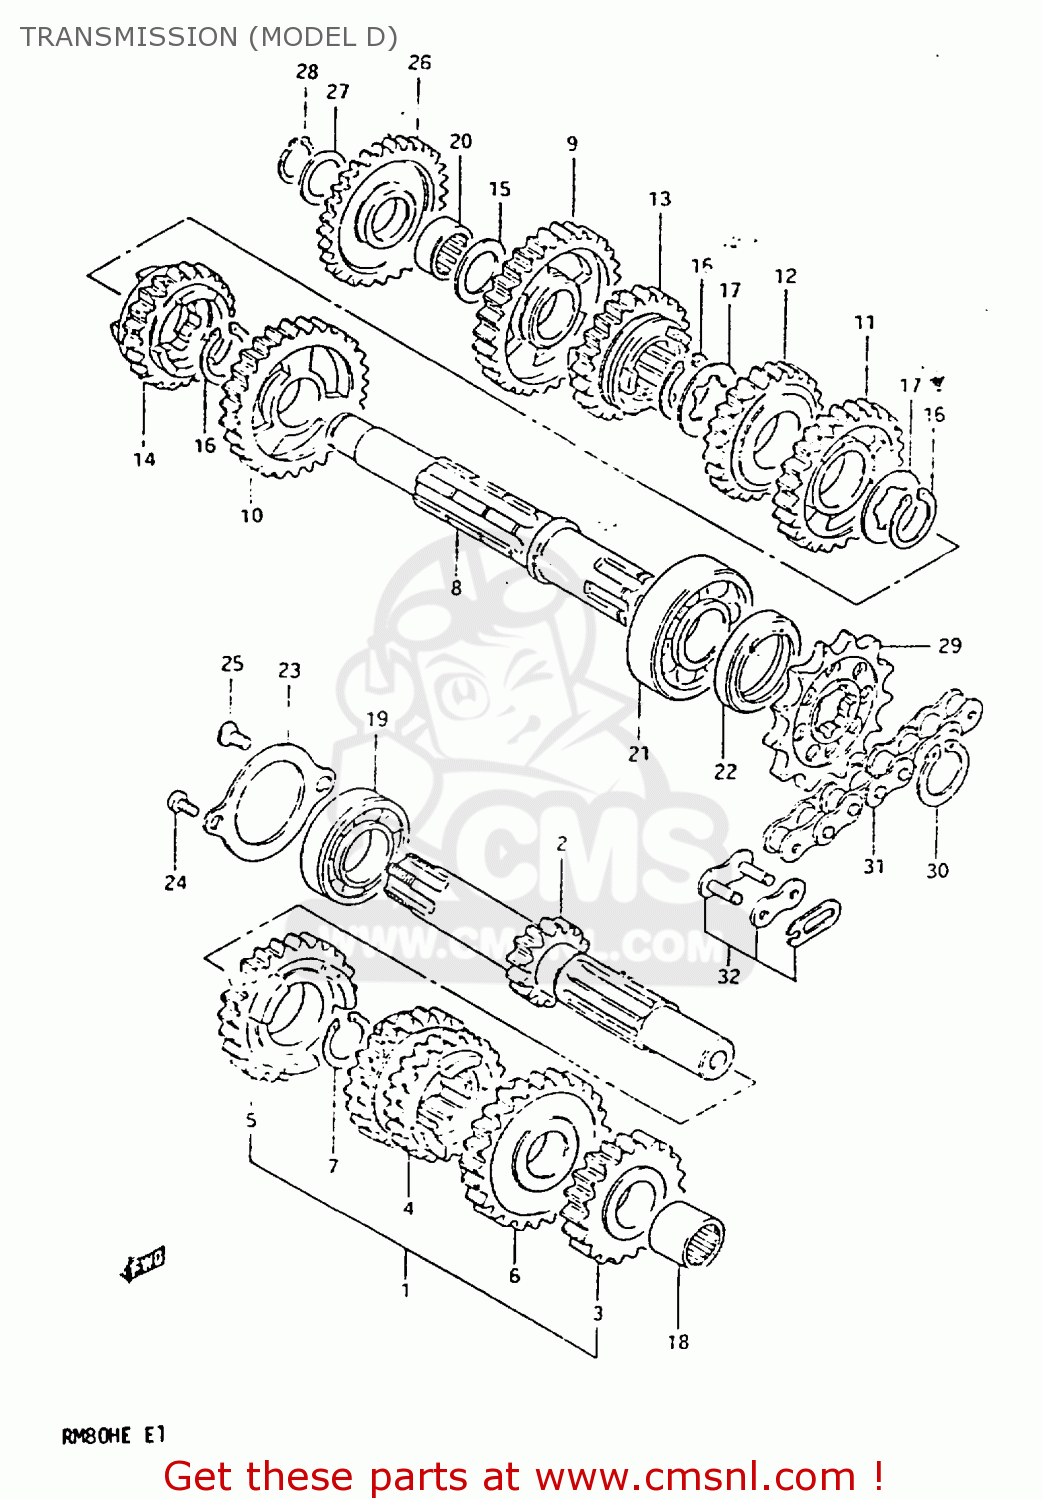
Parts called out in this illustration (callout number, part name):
1	SHAFT,COUNTER
2	SHAFT,COUNTER
3	GEAR,SECOND DRIVE
4	GEAR,THIRD/FOURTH DRIVE
5	GEAR,FIFTH DRIVE
6	GEAR,SIXTH DRIVE
7	CIRCLIP
8	SHAFT,DRIVE
9	GEAR,FIRST DRIVEN
10	GEAR,SECOND DRIVEN
11	GEAR,THIRD DRIVEN
12	GEAR,FOURTH DRIVEN
13	GEAR,FIFTH DRIVEN
14	GEAR,SIXTH DRIVEN
15	WASHER
16	CIRCLIP
17	WASHER,LOCK
18	ROLLER BEARING (13X19X1
19	BEARING
20	BEARING(15X21X12)
21	Bearing
22	OIL SEAL (20X35X5)
23	RETAINER,CNTR SHAFT BEARING
24	SCREW
25	SCREW
26	GEAR,KICK STARTER IDLER(NT:26)
27	THRUST WASHER
28	CIRCLIP
29	SPROCKET,ENGINE
30	CIRCLIP
31	CHAIN ASSEMBLY,DRIVE
32	JOINT,CHAIN
